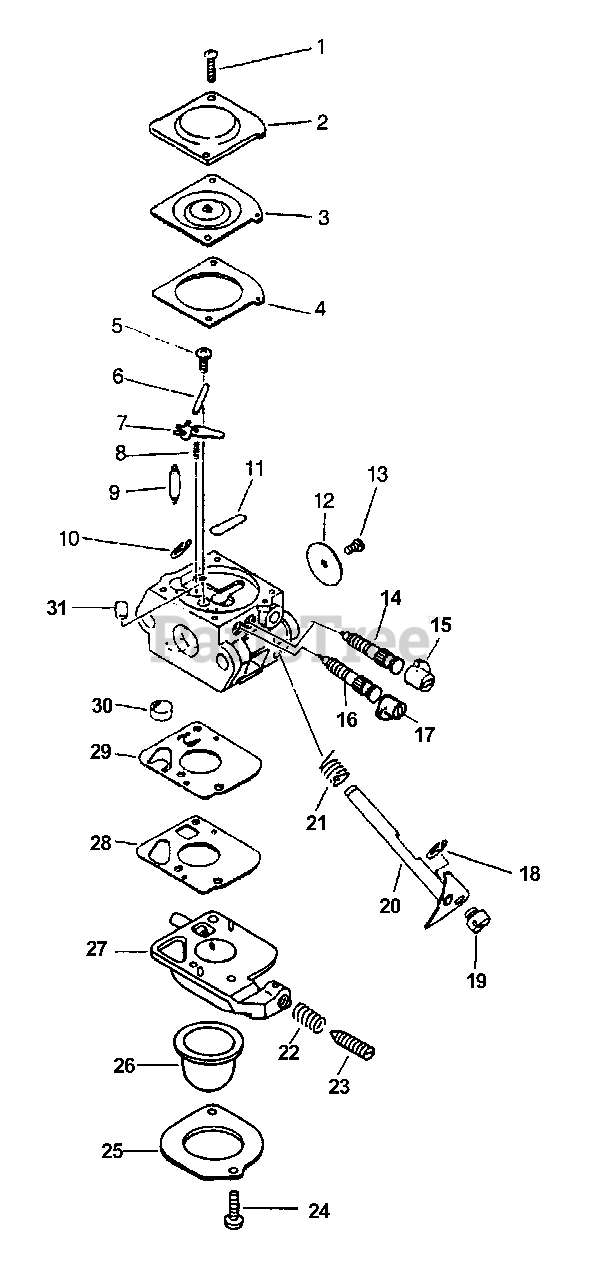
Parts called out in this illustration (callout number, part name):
2	COVER, METERING
3	DIAPHRAGM, METERING
4	GASKET, METERING
5	SCREW, METERING LEVER PIN
6	PIN, METERING LEVER
7	LEVER, METERING
8	SPRING, METERING LEVER
9	VALVE, NEEDLE
10	RING, RETAINING
11	PLUG, WELCH
12	VALVE, THROTTLE
14	NEEDLE - LOW SPEED
15	CAP, LIMITER
16	NEEDLE - HIGH SPEED
17	CAP, LIMITER
18	RING, RETAINING
20	SHAFT, THROTTLE
21	SPRING, RETURN
22	SPRING, IDLE ADJUST
23	SCREW, IDLE ADJUST
24	SCREW, RETAINER
25	RETAINER, PURGE BULB
26	BULB, PURGE
27	BASE, PURGE
28	GASKET, PUMP
29	DIAPHRAGM, PUMP
30	STRAINER
31	NOZZLE, CHECK VALVE
